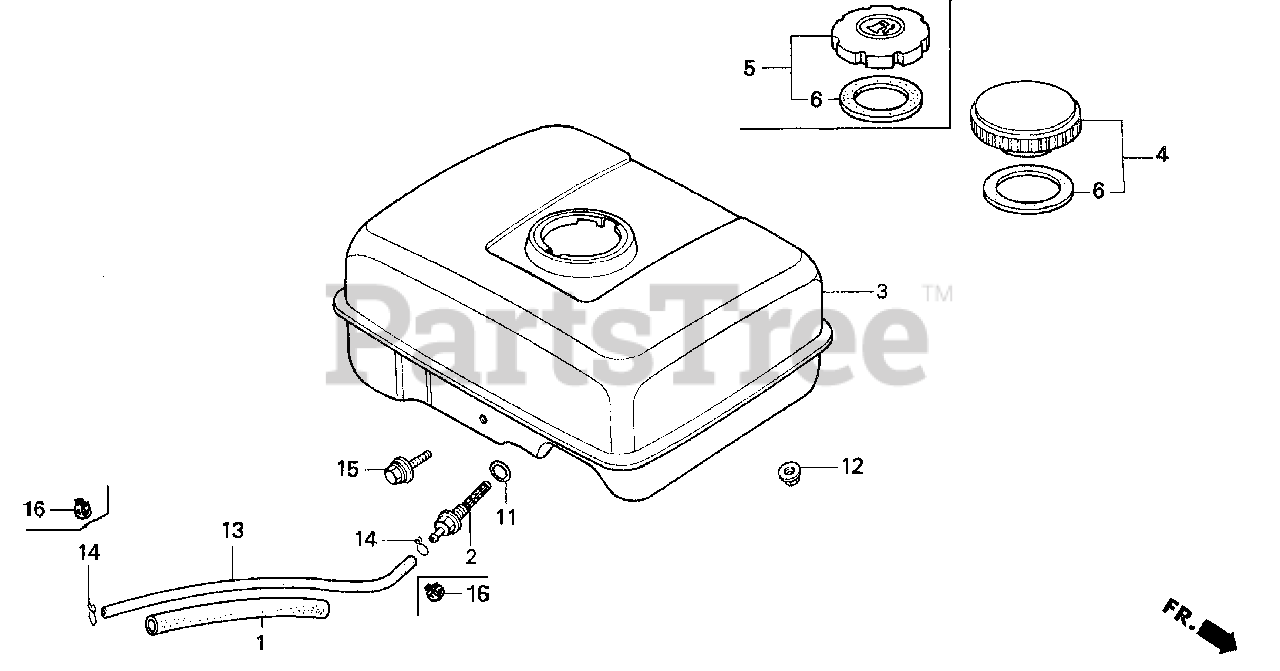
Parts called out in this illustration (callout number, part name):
1	RUBBER, SUPPORTER (107MM)
2	JOINT, FUEL TANK
3	TANK, FUEL *NH31* (MCKINLEY WHITE)
5	CAP, FUEL FILLER (NA USE ALT:17620-Z4H-020)
6	GASKET, FUEL FILLER CAP (39X62X3) (RADICON)
11	O-RING (14MM) (ARAI)
11	O-RING (14MM) (NOK)
12	NUT, FLANGE (6MM)
13	TUBE, FUEL (4.5X140) (FKM)
15	BOLT, FLANGE (6X29)
16	CLAMP, TUBE (D8)
